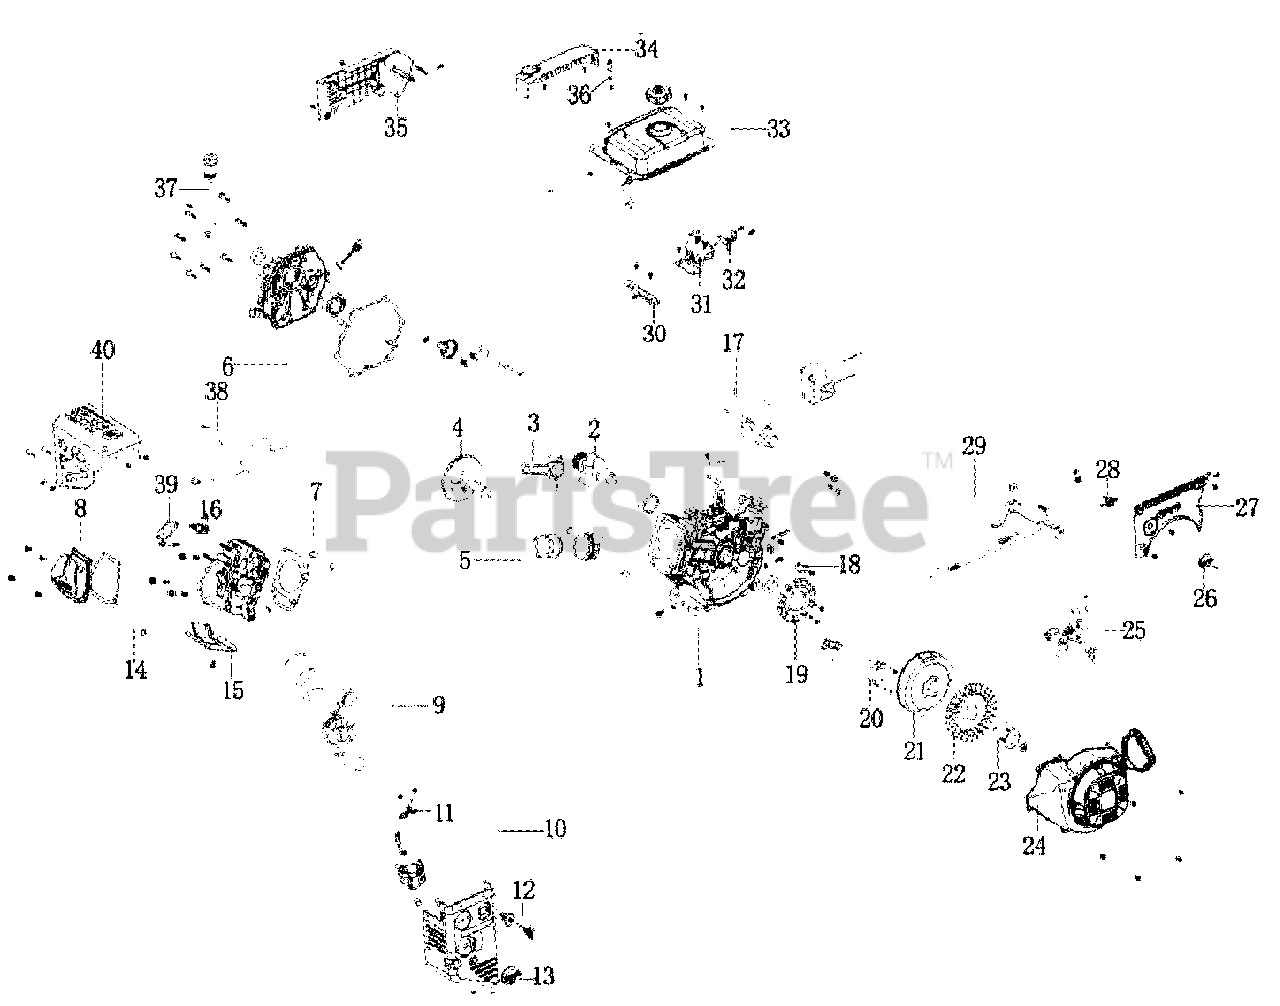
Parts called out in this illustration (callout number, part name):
1	CRANK CASE
2	CRANKSHAFT COMP
3	ROD ASSY ., CONNECTING
4	CAMSHAFT ASSY
5	PISTON
6	CRANK CASE COVER
7	HEAD COMP .,CYLINDER
8	COVER COMP ., HEAD
9	CARBURETOR
10	AIR CLEANER
11	CHIOKE SET
12	KEY SWITCH
13	CHOKE LEVER
14	TUBE , BREATHER
16	PLUG , SPARK
17	STARTER,MOTOR
18	PLATE,WINDING
19	COIL ASSY .
20	COIL ASSY . , IGNITION
21	FLYWHEEL COMP
22	FAN COOLING
23	PULLEY,STARTER
24	STARTER ASSY.
25	CONTROL ASSY.
26	KNOB FUEL SWITCH
27	COVER, ENGINE
28	FUEL SWITCH
29	ARM, GOVERNOR
30	HOLDER,FUEL TANK
31	HOLDER,FUEL TANK
32	HOLDER,ELECTRIC STARTING BOX
33	TANK COMP ., FUEL
34	REAR SOVER TANK
35	COVER, ENGINE
36	A HANGER
37	CAP ASSY.
38	SHROUD
39	GASKET , EX.PIPE
40	MUFFLER
